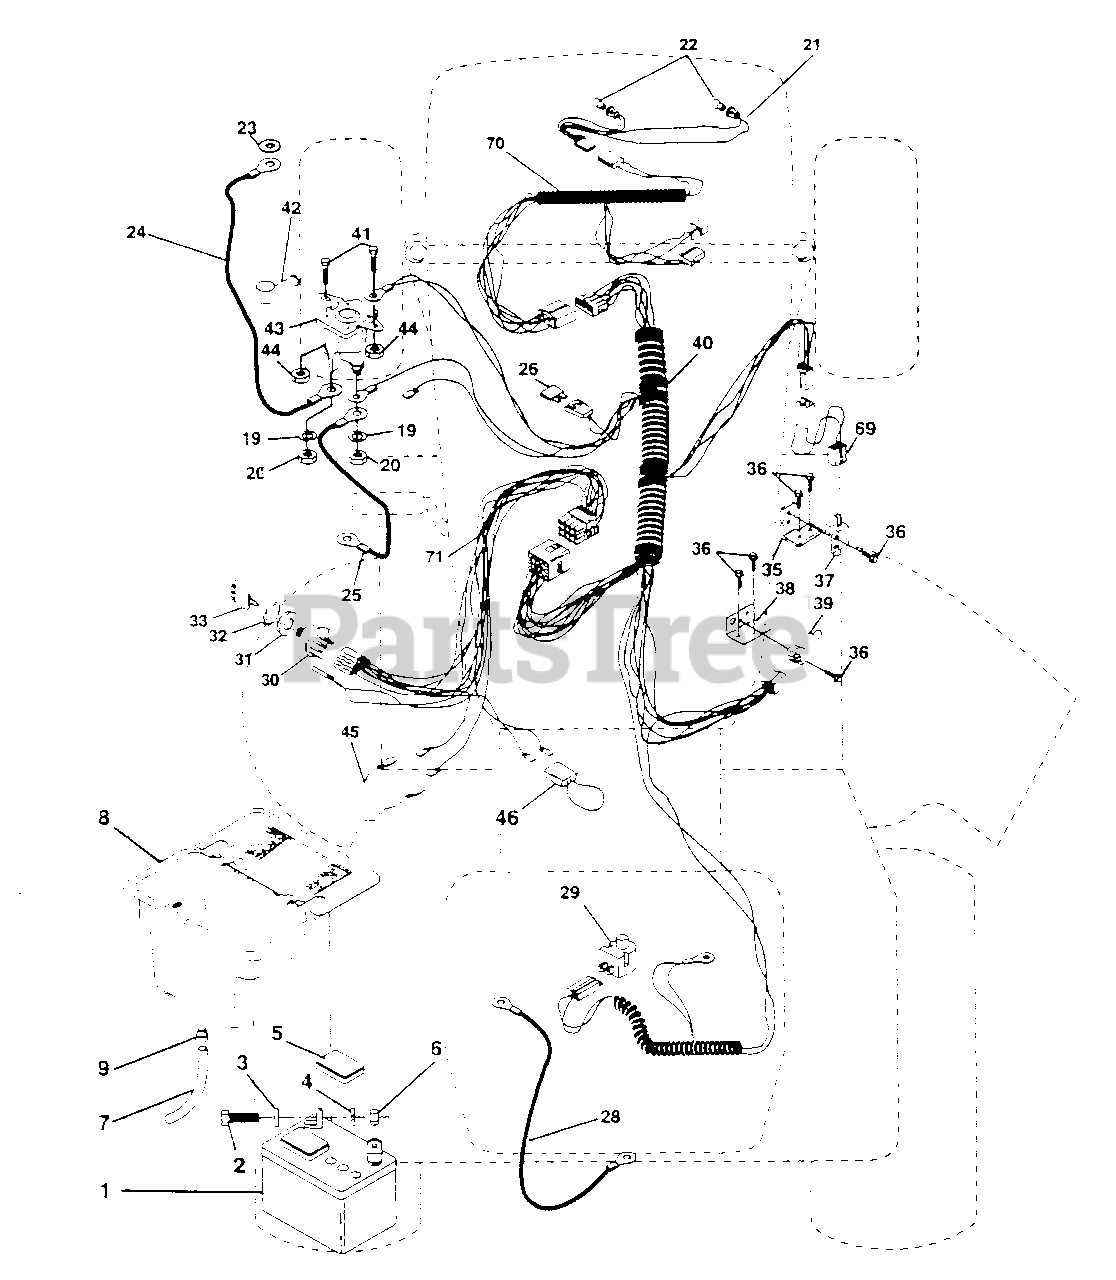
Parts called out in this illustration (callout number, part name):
1	Battery 12 Volt 25 AMP (AYP part number)
2	Bolt Hex Hd 1/4-20unc X 3/4 (AYP part number)
3	Washer 9/32 X 5/8 X 16 Ga. (AYP part number)
4	Washer Lock Hvy Helical 1/4 (AYP part number)
5	Caps Battery 20/25/30 AMP (AYP part number)
6	Nut Fin Hex 1/4-20 Unc (AYP part number)
7	Tube Plastic 12" (AYP part number)
8	Case Battery Hng Mech W/lid (AYP part number)
9	Clamp Hose Olive (AYP part number)
19	Washer Lock 1/4 (AYP part number)
20	Nut Jam Hex 1/4-20 Unc (AYP part number)
21	Harness Asm Light W/4152j (AYP part number)
22	Bulb Light #1156 (AYP part number)
23	Washer Lock Internal Tooth 1/4 (AYP part number)
24	Cable Battery 6 Ga 11" red (AYP part number)
25	Cable Battery 6 Ga 43" red (AYP part number)
26	Fuse 30 AMP Auto Green (AYP part number)
28	Cable Ground 6 Ga 12" black (AYP part number)
29	Switch Plunger Nc Gray (AYP part number)
30	Switch Ign 4 pos w/lights (AYP part number)
31	Nut Ignition (AYP part number)
32	Cover Sw Ignition (AYP part number)
33	Key Ign Modleded Generic (AYP part number)
35	Bracket Switch Clutch (AYP part number)
36	Screw Tap Hex #10-24unc X 1/2 (AYP part number)
37	Switch Intlk Clutch Red 2 Term (AYP part number)
38	Bracket, Switch, Interlock (AYP part number)
39	Switch Intlk Clutch Red 4 Term (AYP part number)
40	Harness Chassis LT PL Mech (AYP part number)
41	Bolt Blk Fin Hex 1/4 - 20 x 1/2 (AYP part number)
42	Cover Terminal Red (AYP part number)
43	Solenoid (AYP part number)
44	Nut Keps Hex 1/4-20 Unc (AYP part number)
45	Adapter Ammeter Rectangular (AYP part number)
46	Protection Wire Loop
69	Harness Adapter Serv Geardrive (AYP part number)
70	Harness, Eng. (AYP part number)
71	Harness Dash Lt Private Lbl (AYP part number)
